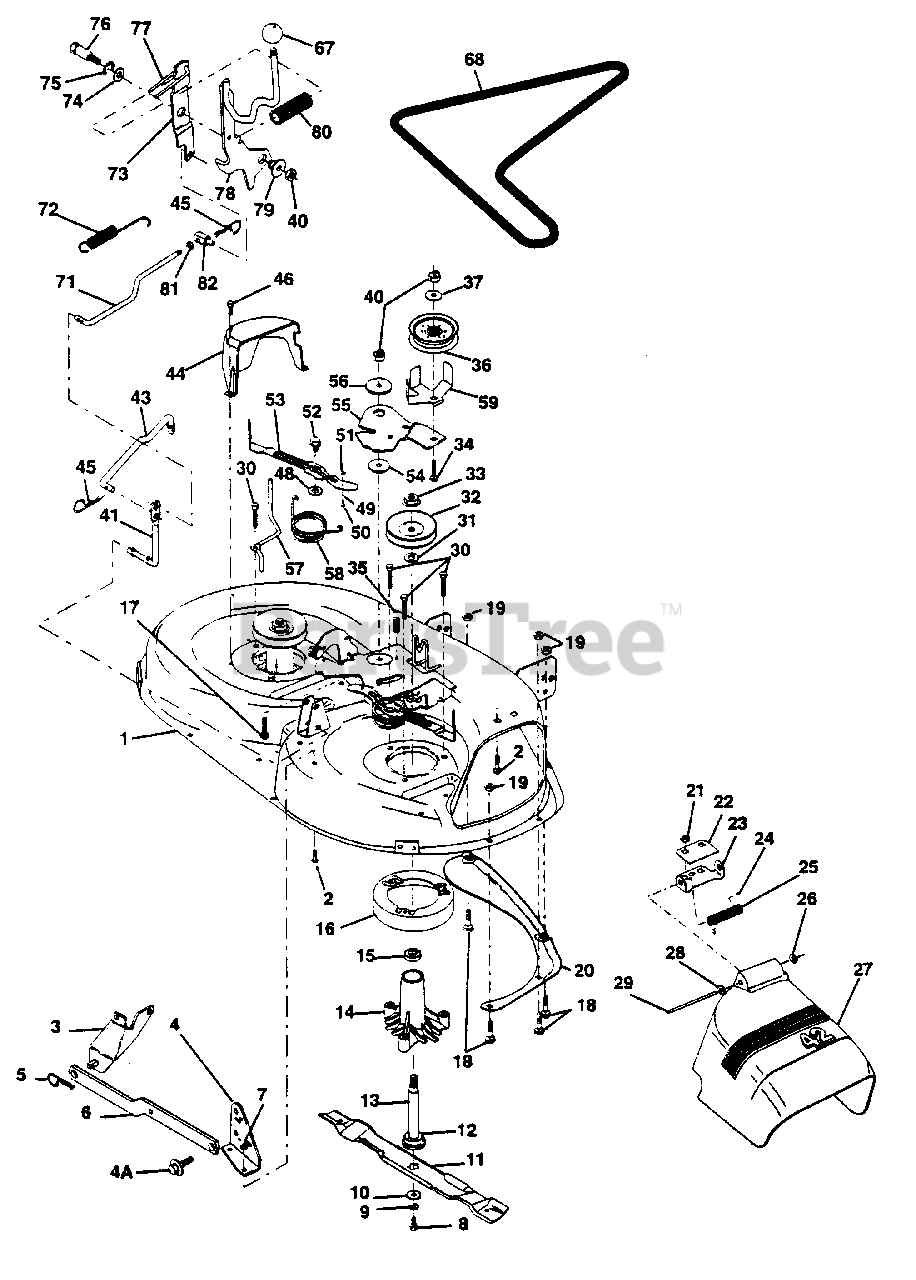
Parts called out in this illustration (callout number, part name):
1	Deck Asm MWR 42"weldment (AYP part number)
2	Bolt Rdhd Sqnk 5/16-18unc X3/4
3	Bracket Asm Fr Sway Bar 38/42 (AYP part number)
4	Bracket Asm Deck 42"sway Bar (AYP part number)
4A	Bolt Shoulder (AYP part number)
5	Retainer Spring (AYP part number)
6	Arm Suspension Rear (AYP part number)
7	Locknut-hex W/ins 5/16-18unc P (AYP part number)
8	Bolt 3/8 - 24 X 1.25 Gr 8 (AYP part number)
9	Washer Lock Hvy 3/8 (AYP part number)
10	Washer Hard Blade Mower Vented (AYP part number)
11	Blade Mower Mulching 42"
12	Bearing Ball #6024 (Mandrel) (AYP part number)
13	Shaft Asm W/lower Bearing
14	Housing Mandrel Vented
15	Bearing Ball Mandrel (AYP part number)
16	Stripper Mower Vented (AYP part number)
17	Bolt Rdhd Sqnk 3/8-16 X 1-1/4
18	Bolt Rdhd Sqnk 5/16-18 X 5/8 (AYP part number)
19	Locknut-hex W/ins 5/16-18unc P (AYP part number)
20	Baffle Vortex 42 (AYP part number)
21	Nut Lock Hex W/Ins 5/16-18 (AYP part number)
22	Stiffener Bracket 42"deck (AYP part number)
23	Bracket Deflector Mower 42" (AYP part number)
24	Cap Sleeve 80x 112 Blk Mower (AYP part number)
25	Spring Torsion Deflector 2 52 (AYP part number)
26	Nut Push Phos & Oil (AYP part number)
27	Shield Deflector Mower 42" Blk (AYP part number)
28	Washer 11/32 X 5/8 X 16 Ga (AYP part number)
29	Rod Hinge 42"6 75 Wlg (AYP part number)
30	Screw Thdrol Hex Head Zinc Mwr (AYP part number)
31	Washer Spacer Mower Vented (AYP part number)
32	Pulley Mandrel 42" (AYP part number)
33	Nut 9/16 Toplock Flng Oil Dip
34	Bolt Rdhd 3/8-16uncx1-3/4 Gr5 (AYP part number)
35	Fastner Christmas Tree (AYP part number)
36	Pulley Idler Flat 3 060 (AYP part number)
37	Washer 13/32 X 13/16 X 16 (AYP part number)
40	Nut Lock Hex W/Ins 3/8-16 Unc (AYP part number)
41	Rod Pivot W/nibs (AYP part number)
43	Rod Clutch Secondary W/nibs (AYP part number)
44	Guard Mandrel LH Black (AYP part number)
45	Spring Retainer 1" Zinc/cad (AYP part number)
46	Screw Hex Thd Cut 1/4-20x5/8 T (AYP part number)
48	Washer Hardened Smaller (AYP part number)
49	Roller Asm Cam Follower 42"dec (AYP part number)
50	Bolt Shldr 10-24 Zinc Gr 5 42" (AYP part number)
51	Nut Lock #10-24 Unc (AYP part number)
52	Bolt Shoulder 5/16-18 Unc Blkz (AYP part number)
53	Arm Asm Pad Brake (AYP part number)
54	Washer Hardened (AYP part number)
55	Arm Idler 42"mower LT/YT (AYP part number)
56	Spacer Retainer Pm Mower (AYP part number)
57	Keeper Belt LH Front (AYP part number)
58	Spring Torsion Brakes (AYP part number)
59	Guard TUV Idler (AYP part number)
67	Knob Rd 1/2-13 Plstc Thds Blk (AYP part number)
68	V-Belt Mower 42" 82 625 (AYP part number)
71	Rod Clutch Primary 38/42 (AYP part number)
72	Spring Return (AYP part number)
73	Arm Clutch Secondary (AYP part number)
74	Washer 25/32 X 1-5/8 X 16 Ga (AYP part number)
75	Ring Klip #t5304-75 (AYP part number)
76	Bolt Shoulder 3/8-16 Unc 1 44 (AYP part number)
77	Keeper Spring 4 000 (AYP part number)
78	Arm Asm Clutch Primary (AYP part number)
79	Bushing 747 Od X 794 Lg Brass (AYP part number)
80	Spring Clutch Mower 2 750 Zinc (AYP part number)
81	Nut Hex Jam 3/8-16 (AYP part number)
82	Trunnion Adj 94 (AYP part number)
